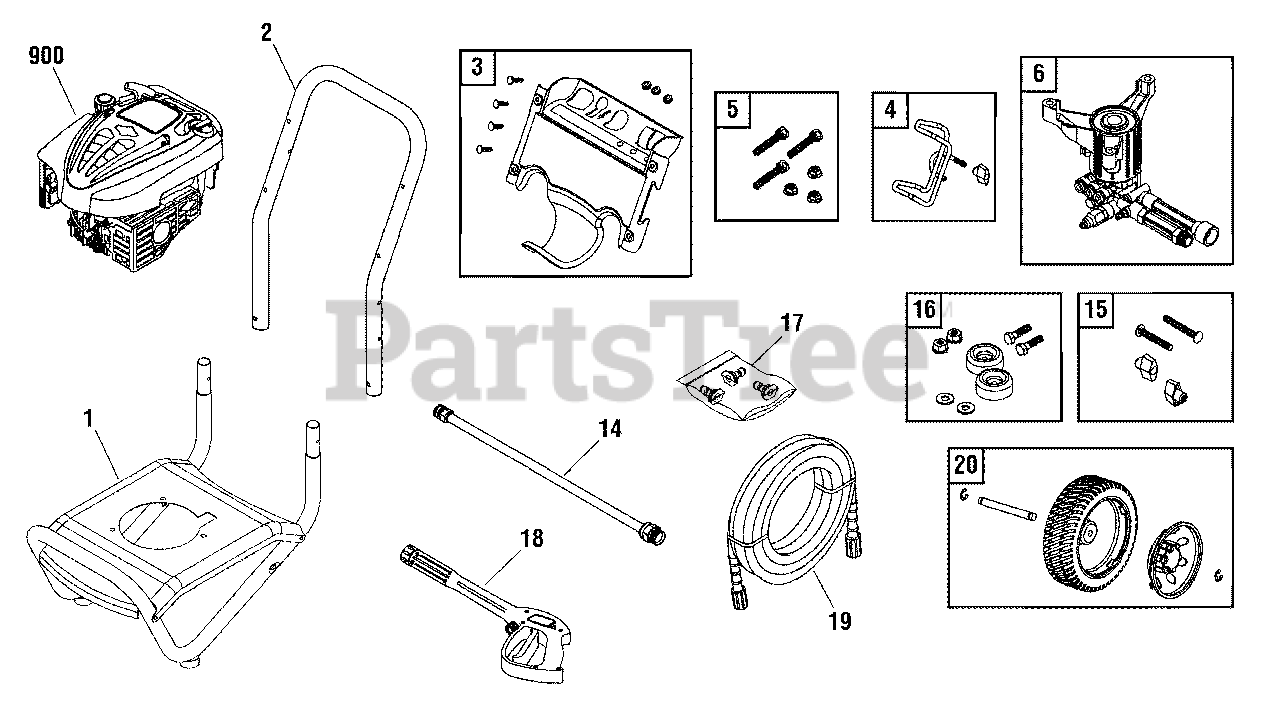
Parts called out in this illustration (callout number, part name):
2	HANDLE
3	ASSY, Billboard w/Decals & Clips
4	KIT, Gun Holder
5	KIT, Pump Mounting Hardware
6	PUMP
14	EXTENSION
15	KIT, Handle Connector
16	KIT, Vibration Mount
18	GUN
19	HOSE
20	KIT, Wheel
900	* ENGINE
